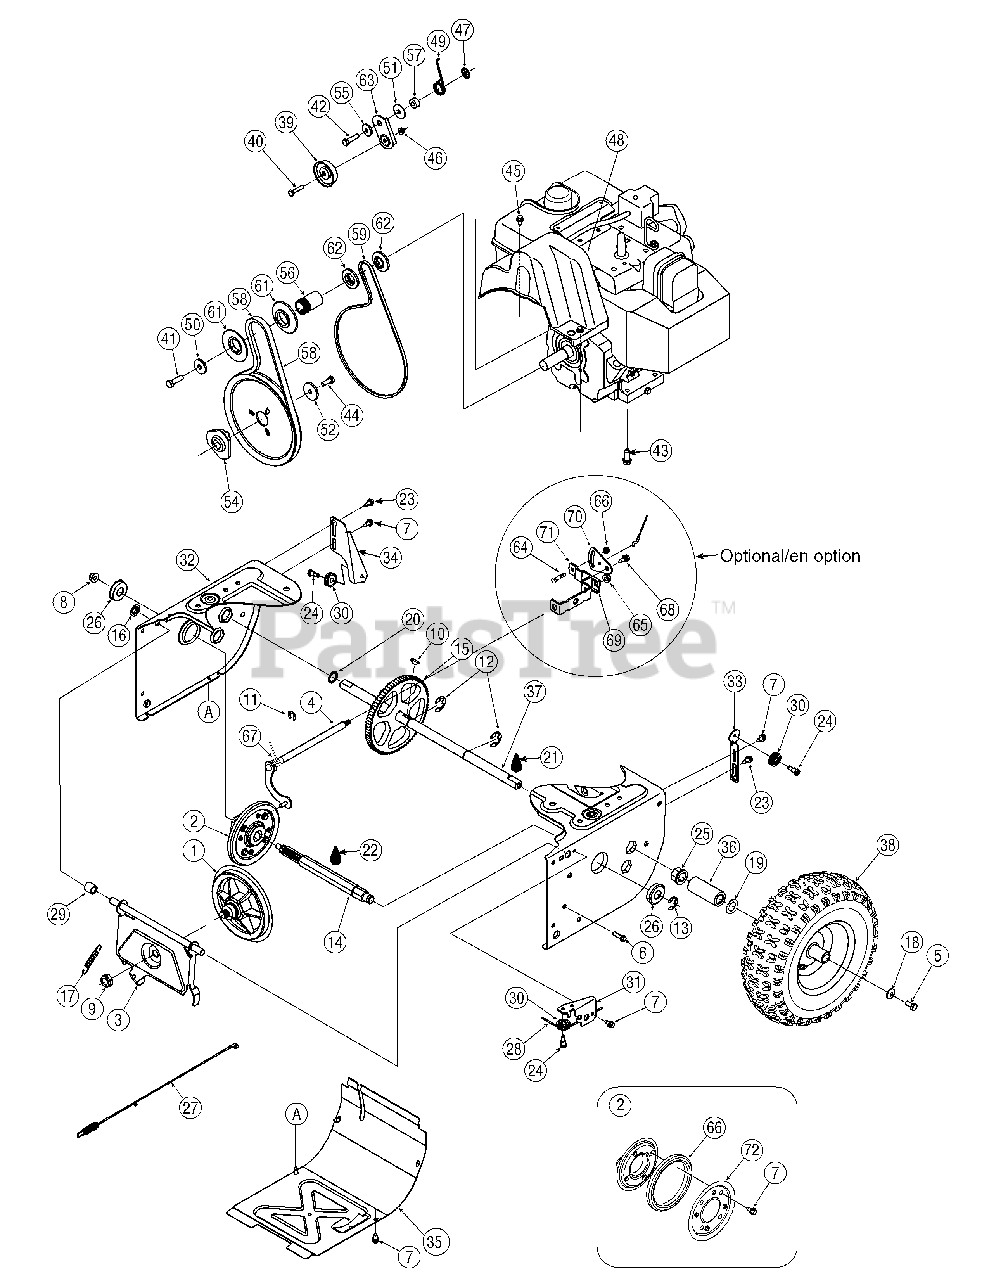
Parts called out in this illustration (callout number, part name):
1	Friction Wheel Disc Assembly
2	Friction Wheel Ass’y, Bearing 5.5 OD
4	Shift Rod Ass’y
5	Hex L-Bolt 5/16-24 x .75 Gr. 5
6	Hex Bolt 1/4-20 x 1.00
7	Hex Wash Hd TT Scr. 1/4-20 x .625
8	Flange Lock-Nut 3/8-16 Gr. F Nylon
9	Jam L-Nut 5/8-18 Gr. 5 Nylon
10	#9 HI-Pro Key 3/16 x 3/4 Dia HT
11	Retaining Ring
12	RetainerRing
13	“E" Ring
14	Hex Shaft .8125 - 7 tooth
15	Gear - 80 Tooth
16	Cap Speed Nut 1/4 Rod
17	Extension Spring 3/8 OD x 2.50
18	Cupped Washer .345 ID x .88 OD x .060
19	Flat Washer .79 ID x 1.25 OD x .06
20	Flat Washer .75 x 1.00 x .06
21	Grease
22	LubricantIndustrial LPS 2
23	Shoulder Screw .373 x .105:TT 1/4-20
24	Hex Shld.Scr.1/4-28 x .375
25	Hex. Flange Bearing.751" ID
26	Ball Bearing w/snap ring
27	Drive Clutch Cable 44.83" Lg.
28	Auger Clutch Cable 47.23" Lg.
29	Spacer .513 ID x 1.0
30	Cable Guide Roller
37	Axle .75 x 22" Lg.
38	Rims
39	Idler Pulley Assembly 1.917 OD
40	Hex Screw 1/4-20 x 1.25
41	Hex Screw 3/8-24 x 1.25
42	Hex Hd Cap Scr. 5/16-24 x 1.25 Gr. 5
43	Hex Wash HD Tap Scr 3/8-16 x .88
44	Hex Bolt 5/16-24 x 0.875
45	Hex Wash Hd TT Scr. 1/4-20 x .625
46	Hex L-Flanged Nut 1/4-20 Gr. F Nylon
47	Push Nut
48	Belt Cover
49	Torsion Spring .850 ID x .354" Lg.
50	Flat Washer .40 ID x 1.25 OD x .160
51	Flat Washer .22 ID x 1.25
52	Flat Washer .34 x 1.50 x .150
53	Grease:Arctic:EP NLGI 1-58F
54	Pulley Adapter
55	ShoulderSpacer
56	Spacer .875 ID x 1.185 OD
57	Spacer .340 x .750 x .360" Lg.
58	Belt .5 x 35.0" Lg.
59	Belt 33.0" Lg.
60	Auger Pulley
61	Pulley Half
62	Pulley Half 1/4 V x 1.5 OD
63	Wheel Drive Idler Bracket
64	Hex Bolt 1/4-20 x .62 Gr. 5
65	Flange Locknut 5/16-18 Gr. F, Nylon
66	Friction Wheel Rubber
67	Torsion Spring .750 ID x .968" Lg.
68	Shoulder Screw .373 x .105:TT 1/4-20
69	Shift Spacer Bracket
72	FrictionPlate
